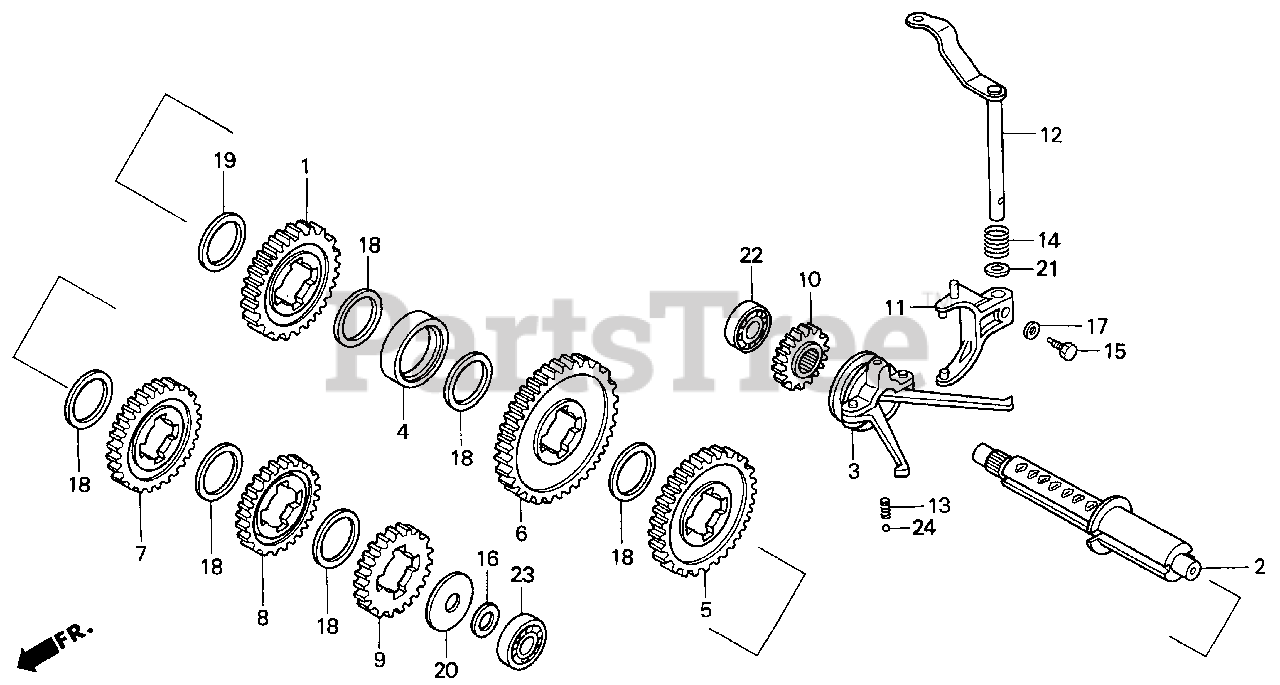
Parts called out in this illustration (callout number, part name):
1	SPROCKET, REVERSE (41T)
2	SHAFT, CHANGE
3	HOLDER, KEY
4	POSITIONER, NEUTRAL
5	GEAR, CHANGE LOW (50T)
6	GEAR, CHANGE LOW (59T)
7	GEAR, CHANGE SECOND (43T)
8	GEAR, CHANGE FOURTH (39T)
9	GEAR, CHANGE FIFTH (36T)
10	GEAR, COUNTERSHAFT DRIVE (20T)
11	FORK, SHIFT
12	SHAFT, SHIFT
13	SPRING, BALL SET
14	SPRING, SHIFT SHAFT
15	BOLT, SPECIAL (8X24)
16	WASHER, THRUST (15MM)
17	WASHER, CONICAL SPRING (8MM)
18	WASHER, DISTANCE (2MM)
19	WASHER, DISTANCE (1MM)
20	WASHER, CHANGE THRUST
21	WASHER (14MM)
22	BEARING, RADIAL BALL (6202)
23	BEARING, RADIAL BALL (6202)
24	BALL, STEEL (#10) (5/16)
